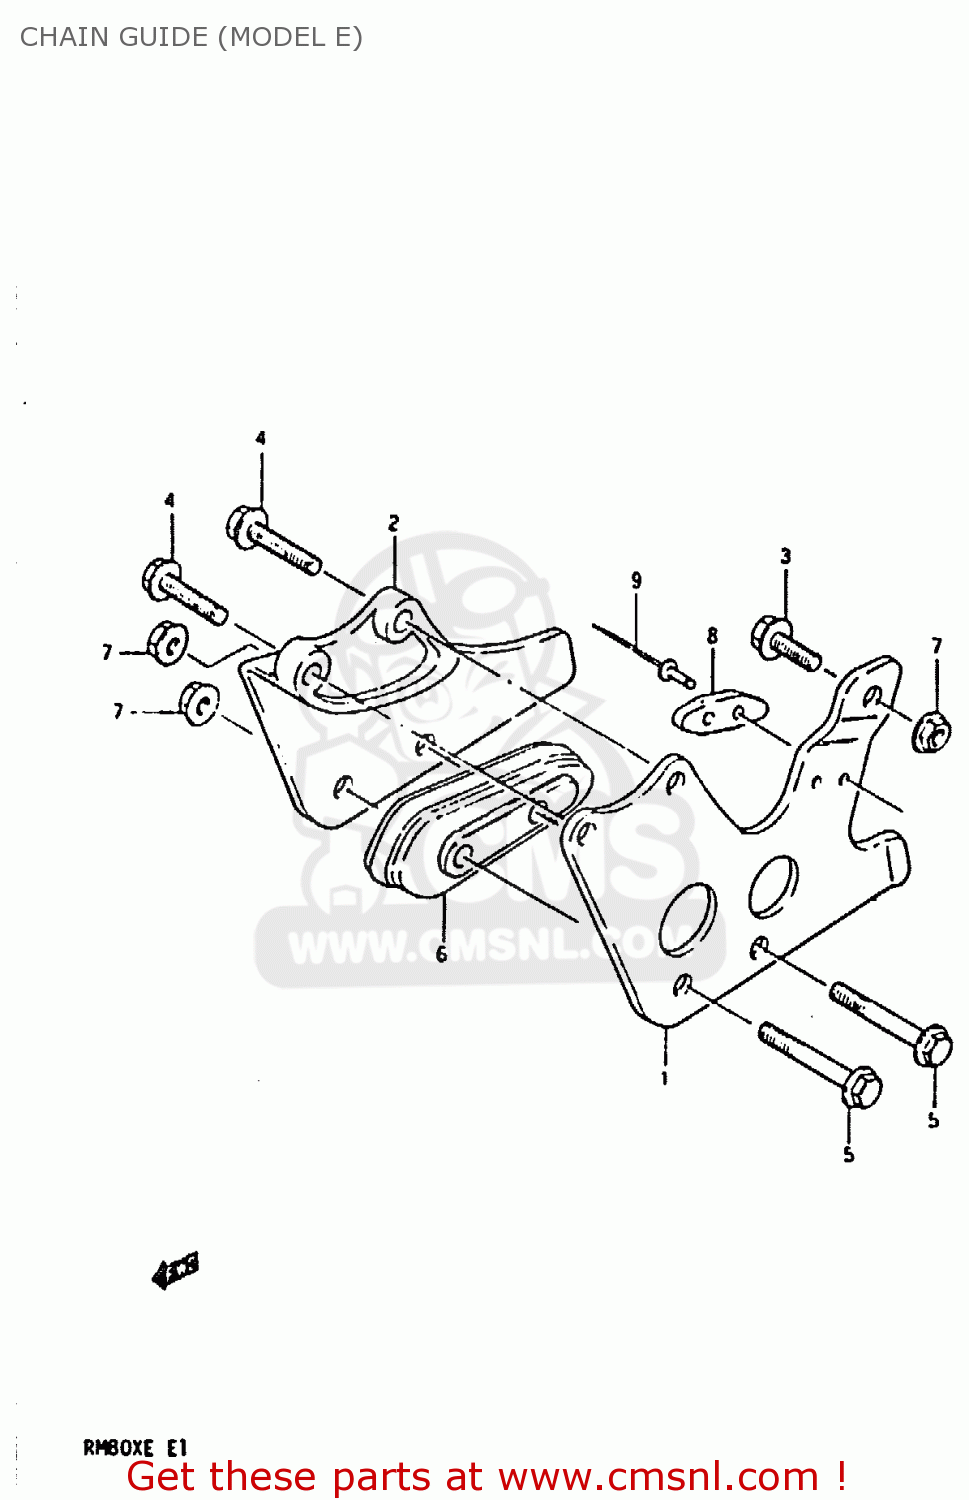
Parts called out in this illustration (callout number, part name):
1	PLATE,CHAIN GUIDE,OUTER
2	PLATE,CHAIN GUIDE INNER
3	BOLT
4	BOLT
5	BOLT
6	DEFENSE,CHAIN GUIDE
7	NUT
8	PAD
9	RIVET
